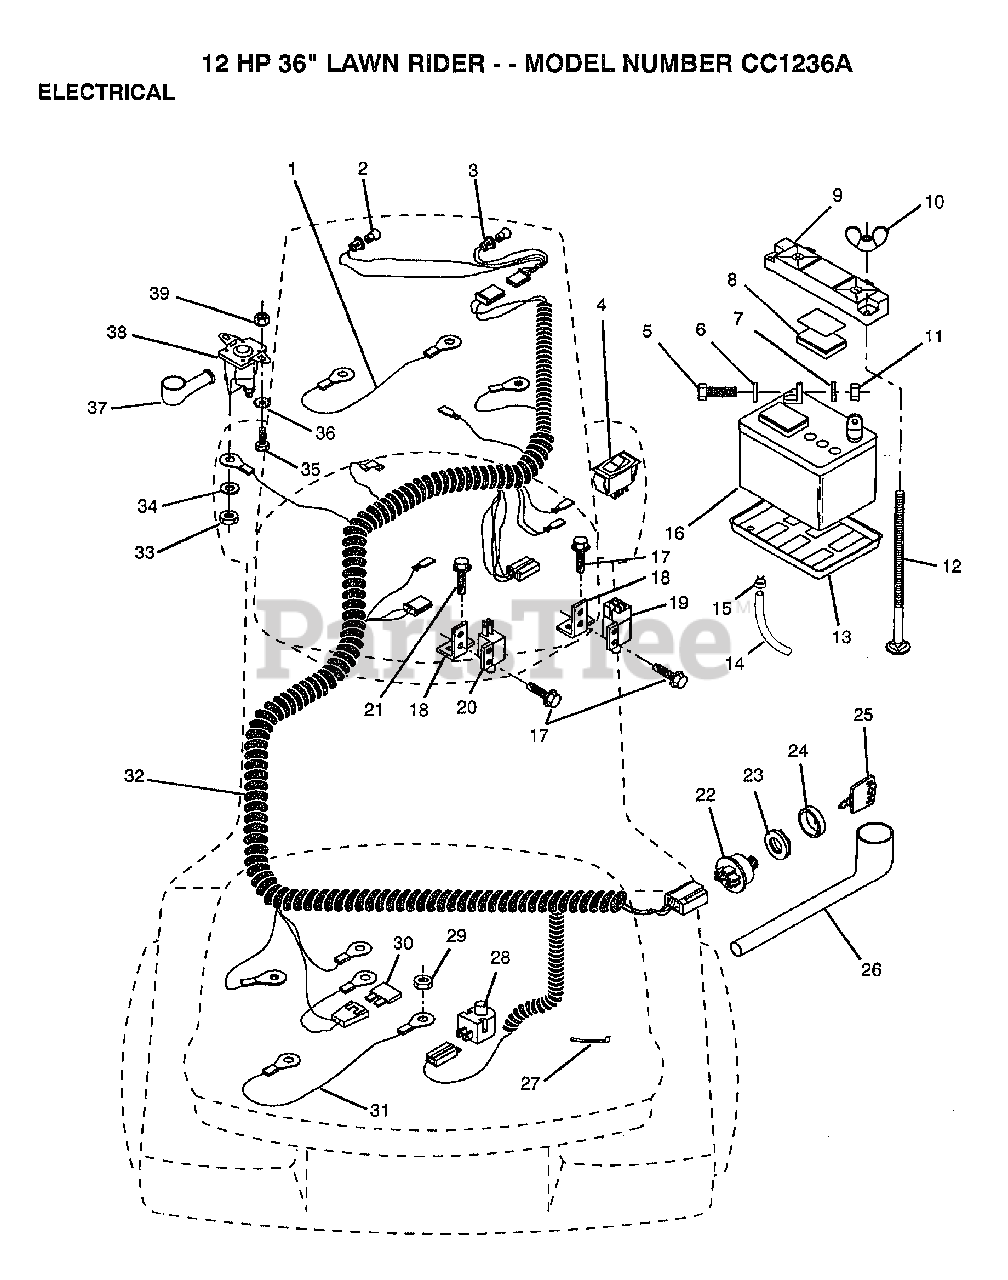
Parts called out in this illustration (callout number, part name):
1	CABLE LTV
4	SWITCH LT
5	BOLT LT
6	WASHER
7	LOCKWASHER
12	BOLT
13	"TRAY T, BATTERY"
15	HOSE CLAMP T
17	SCREW
18	BRACKET LT
19	SWITCH INTERLOCKT
20	SWITCH-INTER. GT
21	SCREW
23	NUT IGNITION
25	KEY
26	COVER IGNITION SW
27	WIRE TIE
28	SWITCH SEAT
30	FUSE HYT
32	HARNESS IGNITION
33	NUT
35	BOLT
39	NUT
